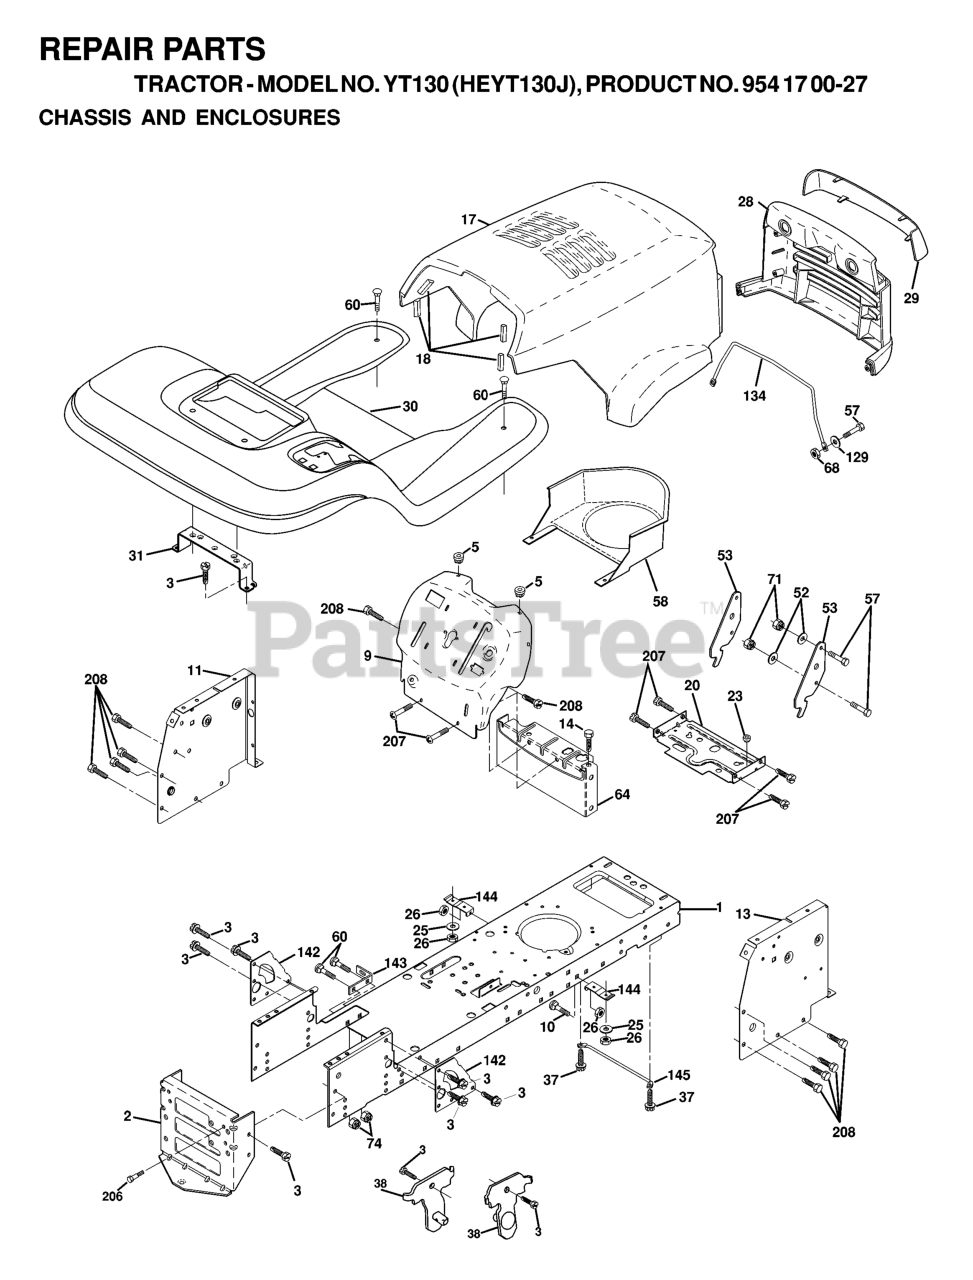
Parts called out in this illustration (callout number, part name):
2	DRAWBAR
3	SCREW 3/8-16X3/4
5	BUMPER.RUBBER.HOOD
9	DASH
10	BOLT D
11	PANEL DASH LH
13	DASH PANEL RH
17	HOOD
18	BUMPER HOOD T
20	PLATE MTG
23	BUSHING.SNAP.NYL.BLK.
25	WASHER
26	NUT
28	GRILL
29	LENS
30	FENDER FOOTREST
31	BRACKET.SUPPORT.FENDER
37	Screw 5/16-18 x 1/2 Hex, Self Tapping 5/16-18 x 1/2
38	BRACKET
51	LOCKNUT.NYLOC.1/4-20
53	BRACKET PNT PICK OFF LT/PL
57	BOLT
58	AIR DUCT P/L/LT
60	Bolt - Rd. Hd. Sq. Neckiage 3/8 16 x 3/4
64	DASH LOWER
68	NUT
71	NUT.CROWNLOCK.1/4
134	ROD SUPPORT HOOD LT/PL HUS.
142	PLATE
143	BRACKET, SWAY BAR
144	BRACKET FOOTREST
145	ROD PIVOT CHASSIS/HOOD
206	SHOULDER BOLT 5/16-18TT
208	SCREW 3/8-16X1/2
